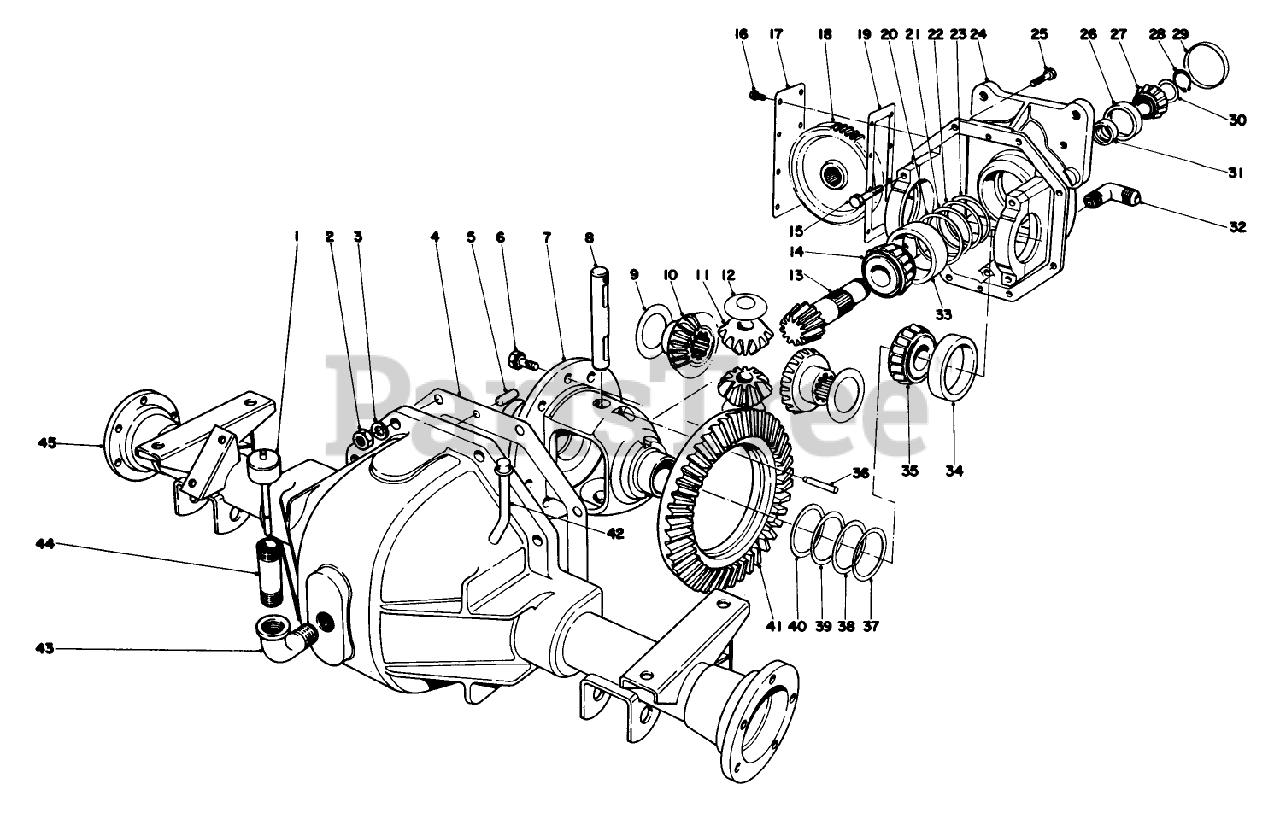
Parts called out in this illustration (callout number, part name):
1	DIPSTICK
2	NUT-HEX
3	WASHER-LOCK
4	HSG GASKET
5	PIN-DOWEL
6	SCREW-GEAR, DRIVE
7	CASE-DIFFERENTIAL
8	SHAFT-MATE, PINION
9	WASHER-THRUST
10	GEAR-DIFFERENTIAL
11	PINION-DIFFERENTIAL
12	WASHER-THRUST, PINION
14	ROLLER BRG CONE
15	SCREW-HH
16	SCREW
17	COVER-GEAR
18	Gear-Spur
19	GEAR COVER GASKET
20	REAR PINION BRG SHIM
21	BRG SHIM .005
22	BRG SHIM .010
23	BRG SHIM .030
24	Upper Housing Assembly
25	Screw
26	BEARING-CUP
27	BRG CONE
28	Retaining Ring
29	PLUG-CUP
30	FRT PINION BRG SHIM
31	SPACER-BEARING
32	90 DEG FITTING
33	ROLLER BRG CUP
34	CUP-BEARING, ROLLER
35	BEARING-ROLLER, CONE
36	Pin-Roll
37	SHIM-BEARING, DIFFERENTIAL (.003)
38	SHIM-BEARING, DIFFERENTIAL (.005)
39	SHIM-BEARING, DIFFERENTIAL (.010)
40	SHIM-BEARING, DIFFERENTIAL (.030)
41	Ring Gear
42	Vent Assembly
43	FITTING-ELBOW-90
44	PIPE NIPPLE
45	Lower Housing Assembly
